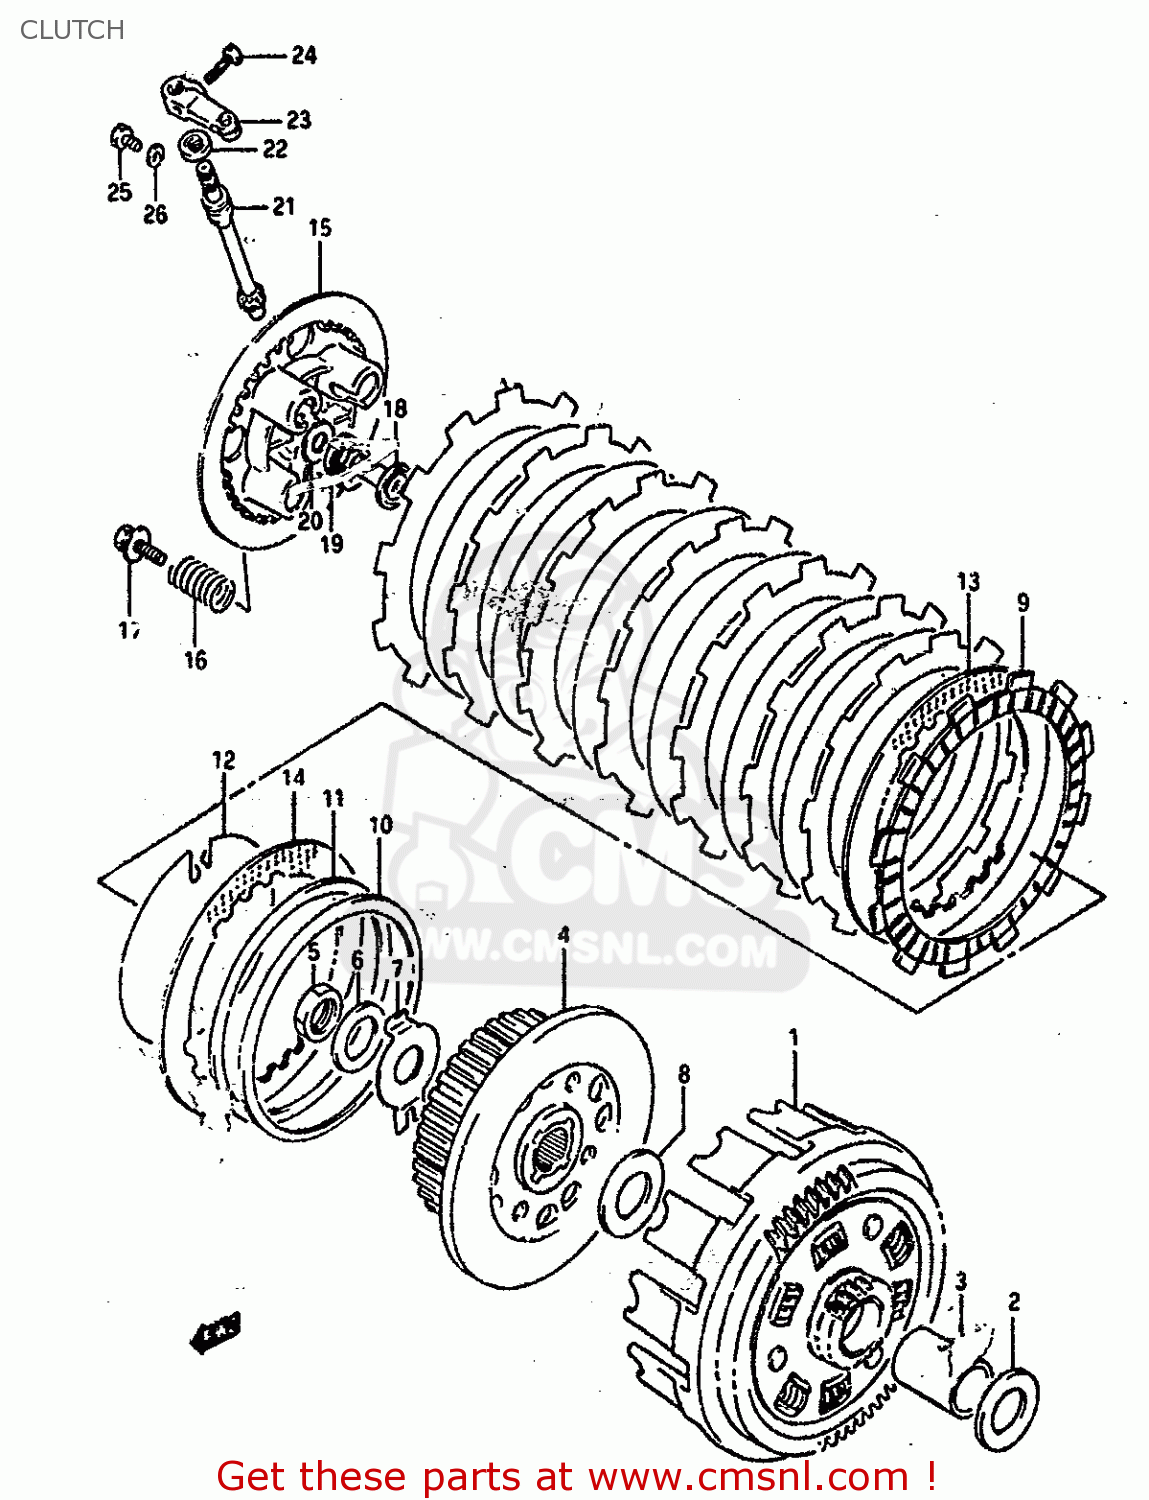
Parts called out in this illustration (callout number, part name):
1	GEAR,PRIMARY DRIVEN (NT:62/20)
2	WASHER(22X38X2)
3	SPACER
4	HUB,CLUTCH SLEEVE
5	NUT (20MM)
6	WASHER
7	WASHER
8	WASHER(22X44X2)
9	PLATE,CLTCH DR
10	SEAT,WAVE WASHER
11	WASHER
12	RING,STOPPER
13	PLATE,CLUTCH DRIVEN NO.1 (NAS)
14	PLATE,CLUTCH DRIVEN (NAS)
15	DISK,PRESSURE
16	SPRING
17	BOLT
18	RACK RELEASE
19	BEARING(10X24X2)
20	WASHER
21	PINION,CLUTCH RELEASE
22	SEAL,OIL(10X17X5)
23	ARM,CLUTCH RELEASE
24	BOLT
25	BOLT
26	GASKET(6.2X11X1).2 (NAS)
